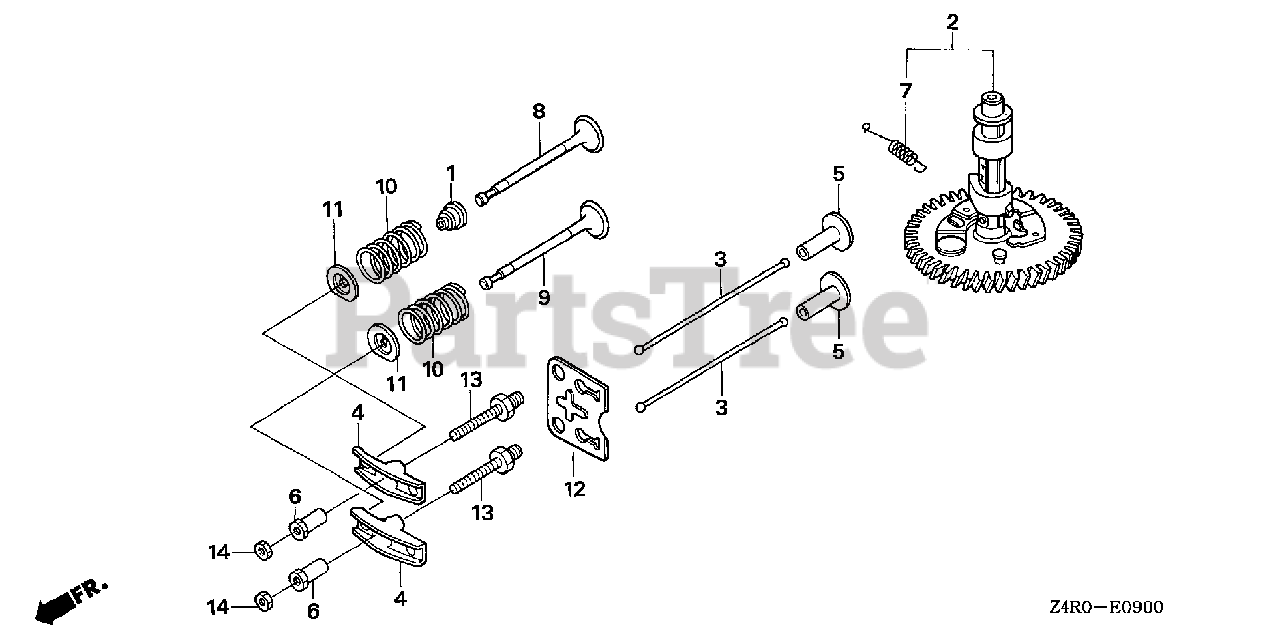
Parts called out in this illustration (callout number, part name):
1	SEAL, VALVE STEM
2	CAMSHAFT ASSY.
3	ROD, PUSH
4	ARM, VALVE ROCKER
5	LIFTER, VALVE
6	PIVOT, ROCKER ARM
7	SPRING, WEIGHT RETURN
8	VALVE, IN.
9	VALVE, EX.
10	SPRING, VALVE
11	RETAINER, IN. VALVE SPRING
12	PLATE, PUSH ROD GUIDE
13	BOLT, PIVOT (8MM)
14	NUT, PIVOT ADJUSTING
